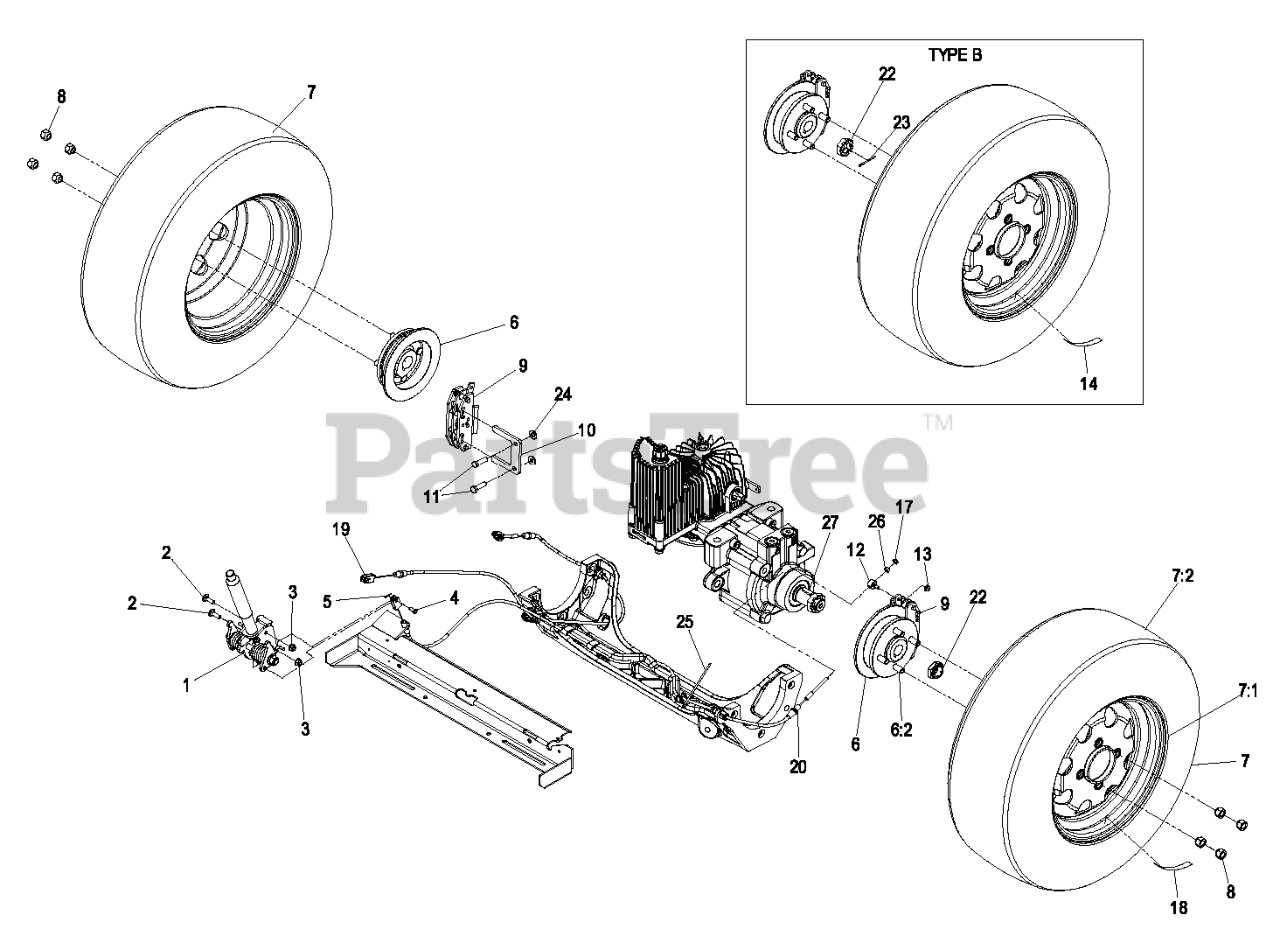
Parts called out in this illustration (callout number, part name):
1	BRAKE HANDLE ASM
2	BOLT-CARR
3	NUT-HF, NI
4	PIN-CLEVIS
5	PIN-COTTER
6:2	STUD-WHEEL
7	WHEEL AND TIRE ASM
7:1	RIM ASM
8	NUT-LUG
9	CALIPER-BRAKE
10	PLATE-MOUNT, BRAKE
11	SCREW-LOCK, PATCH
14	DECAL-HUB, WHEEL
17	NUT-LOCK, NI
23	PIN-COTTER
24	WASHER-FLAT
25	TIE-CABLE
26	NUT-HEX
27	KEY-WOODRUFF
